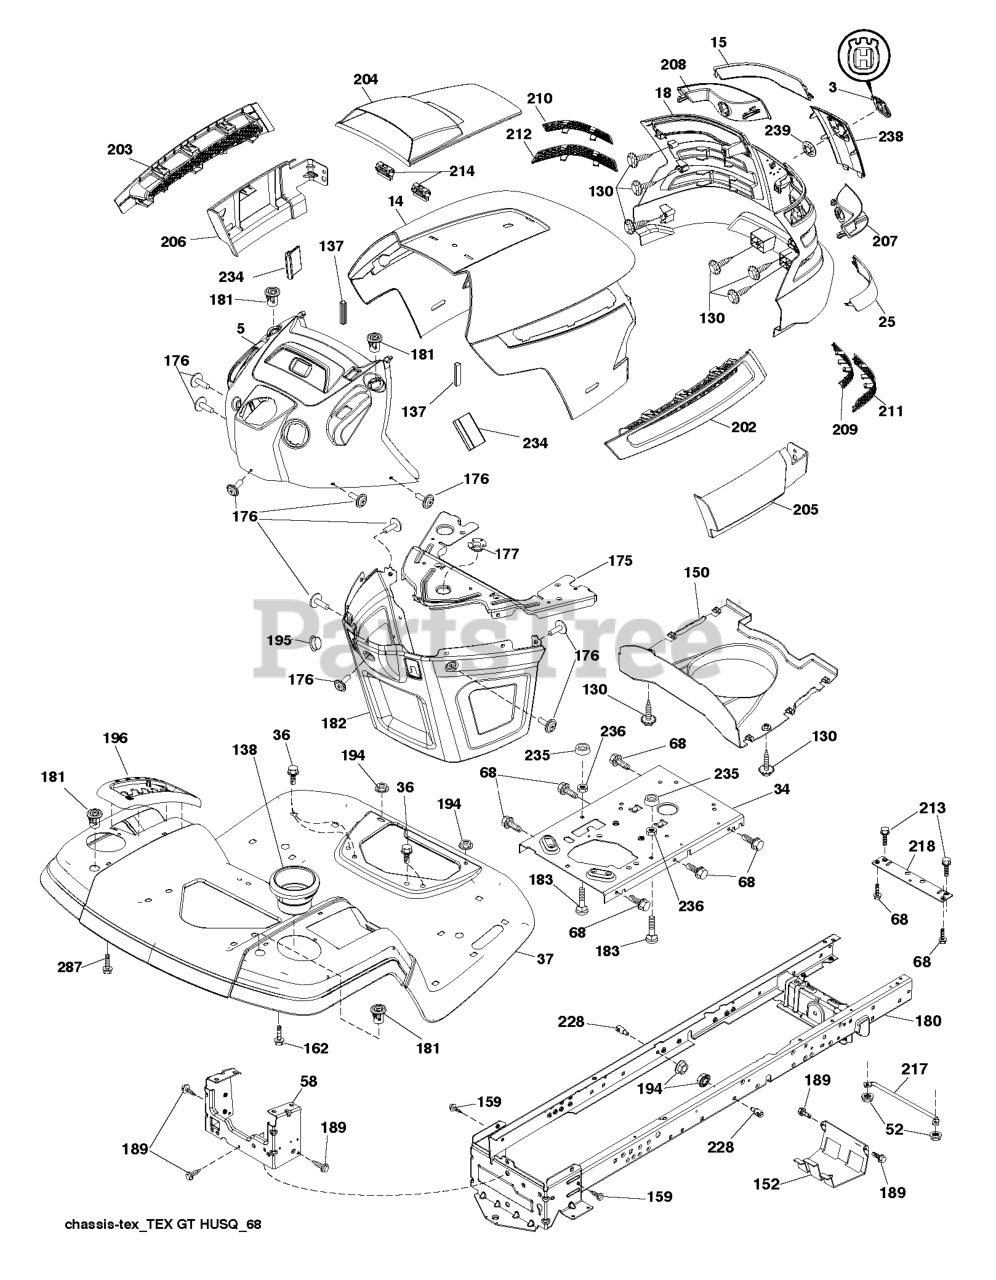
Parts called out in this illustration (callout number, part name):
3	LOGO.HUSQ.GT.LT.CROWN.H
14	HOOD
15	LENS.LH.TEX.GT.HUSQ.CL
18	GRILL.ASM.HUSQ.TG/CRD.W/TRIM
25	LENS.RH.TEX.GT.HUSQ.CL
34	PLATE.ENGINE.WELDED.CHASSIS
36	SCREW 5/16"
37	FENDER
52	LOCKNUT
58	DRAWBAR UPPER 2PC SMALL FENDER
68	Screw 5/16-18 x 1/2 Hex, Self Tapping 5/16-18 x 1/2
130	SCREW.#10 X 0.750.BOS
137	BUMPER DASH
138	CUPHOLDER.TL.TEX.418
150	AIR.DUCT.TEXGT.HUSQ.SV
152	SHIELD.BROWNING.W/TEX
159	SCREW, 3/8-16X3/4
162	SCREW.HI-LO.CONSOLE
175	PLATE.CROSSMEMBER.HUSQ
176	SCREW.#10-24X5/8.RN.QU
177	BUSHING, STEERING
180	CHASS.WLDMNT.TL.12GA/2P.48/54
181	BUSHING.MNT.FEND.CRGO.
182	DASH.LOWER.COMMON.12V.ADAPTOR
183	BOLT.5/16-18X1-1/4 FULL THD
189	SCREW
194	NUT LOCK HEX FLANGE 5/16-18
195	PLUG.HOLE.DASH.LOWER.12V.BLK
196	RP CONSOLE.ASM.DECKLFT.GR/RBT.
202	VENT.SIDE.HOOD.HUSQ.RH.GREY
203	VENT.SIDE.HOOD.HUSQ.LH.GRAY
204	HOOD VENT
205	SKIRT.HOOD.SIDE.HUSQ.RH.GREY
206	SKIRT.HOOD.SIDE.HUSQ.LH.GREY
207	BEZEL.RH.TEX.GT.HUSQ
208	BEZEL.LH.TEX.GT.HUSQ
209	INSERT.HEX.GRILL.HUSQ.GREY
210	INSERT.HEX.GRILL.HUSQ.
211	INSERT.HEX.GRILL.HUSQ.
212	INSERT.HEX.GRILL.HUSQ.
213	BOLT
214	CLIP.RETAINER.TINNER.
217	ROD.PIVOT.HOOD
218	X-PIECE.HOOD.STOP.NON/
228	STUD.FASTNER.W/ANTI-ROTATE
234	BUMPER.HOOD.TEX.HUSQVARNA
235	SPACER FENDER
236	NUT.CENTERLOCK.5/16-
238	TRIM.HUSQ.TG/CRD.SERVICE
239	NUT PUSH M
287	SCREW 1/4X20
